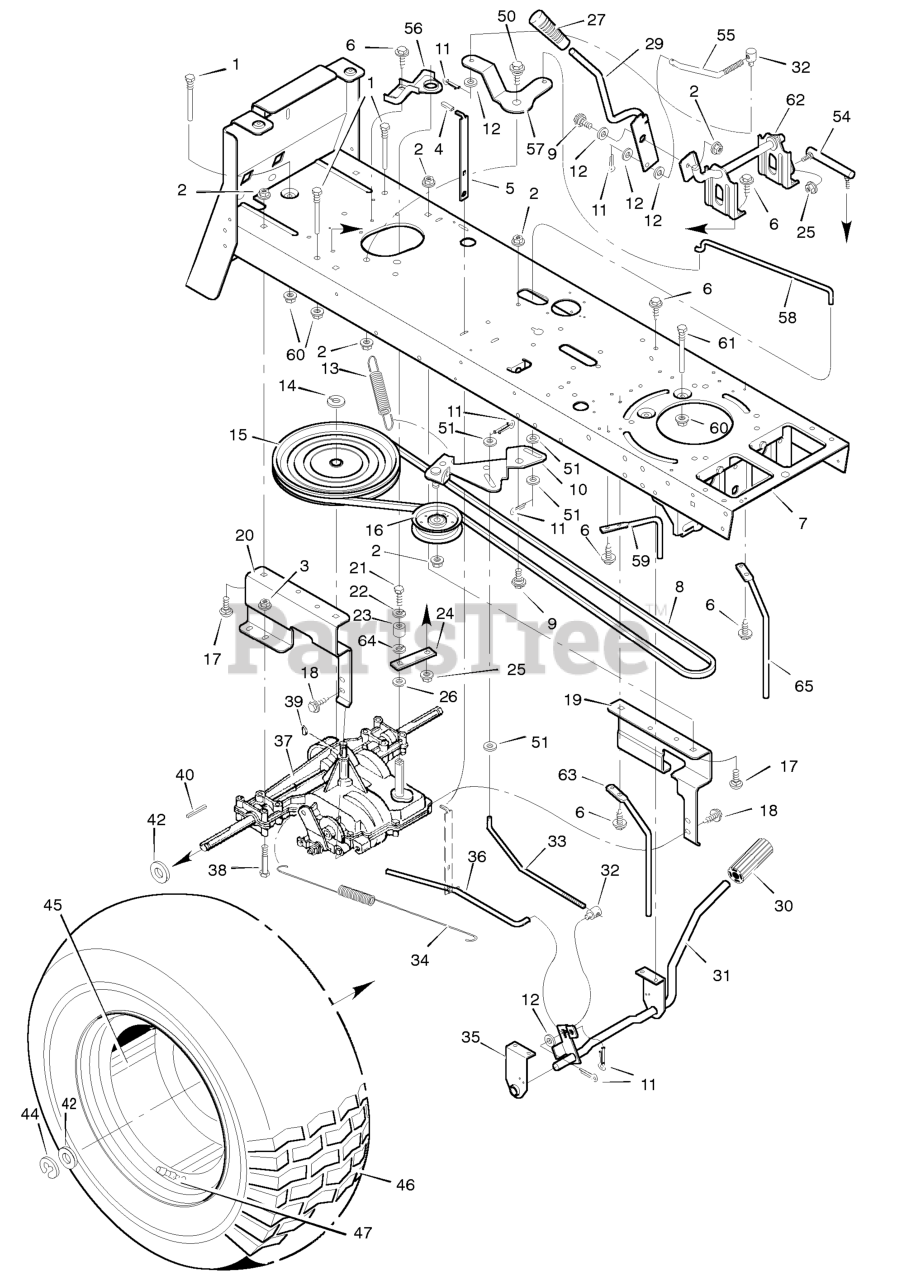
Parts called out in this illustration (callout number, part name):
1	Guide, Belt
2	Locknut, Flange
3	Locknut, Flange
5	Lever, Parking Brake
8	Belt, Motion Drive
9	Bolt, Shoulder
10	Bracket Assembly, Idler
11	Pin, Cotter
12	Washer
13	Spring, Drive Extension
14	Ring, Retainer
15	Pulley, Motion Drive
16	Pulley, Backside Idler
17	Bolt, Carriage
19	Bracket, Left Transaxle
20	Bracket, Right Transaxle
21	Bolt, Hex
22	Lockwasher
23	Pilot, Support
24	Yoke, Shift Lever
25	Locknut
27	Grip
29	Lever, Shift
30	Pedal, Clutch/Brake
31	Lever Assembly, Pedal
32	Nut, Adjustable
33	Rod, Clutch
34	Spring, Brake Extension
35	Bracket, Pedal Support
36	Rod, Brake Latch
37	Transaxle, Peerless **
38	Bolt, Hex
39	Key, Woodruff No. 9
40	Key, Square
42	WASHER, 1-1.3 16G FLT
45	Wheel & Tire Assembly
46	Tire *
47	Valve Stem
50	Bolt, Shoulder
51	Washer
52	Washer
54	Link, Shifter
55	Link, Clutch
56	Bracket, Support
57	Bracket, Pivot
58	Rod, Clutch
59	Guide, Belt
60	Nut, Flange
61	Guide, Belt
62	Shifter Assembly
63	Guide, Belt
65	Guide, Belt
